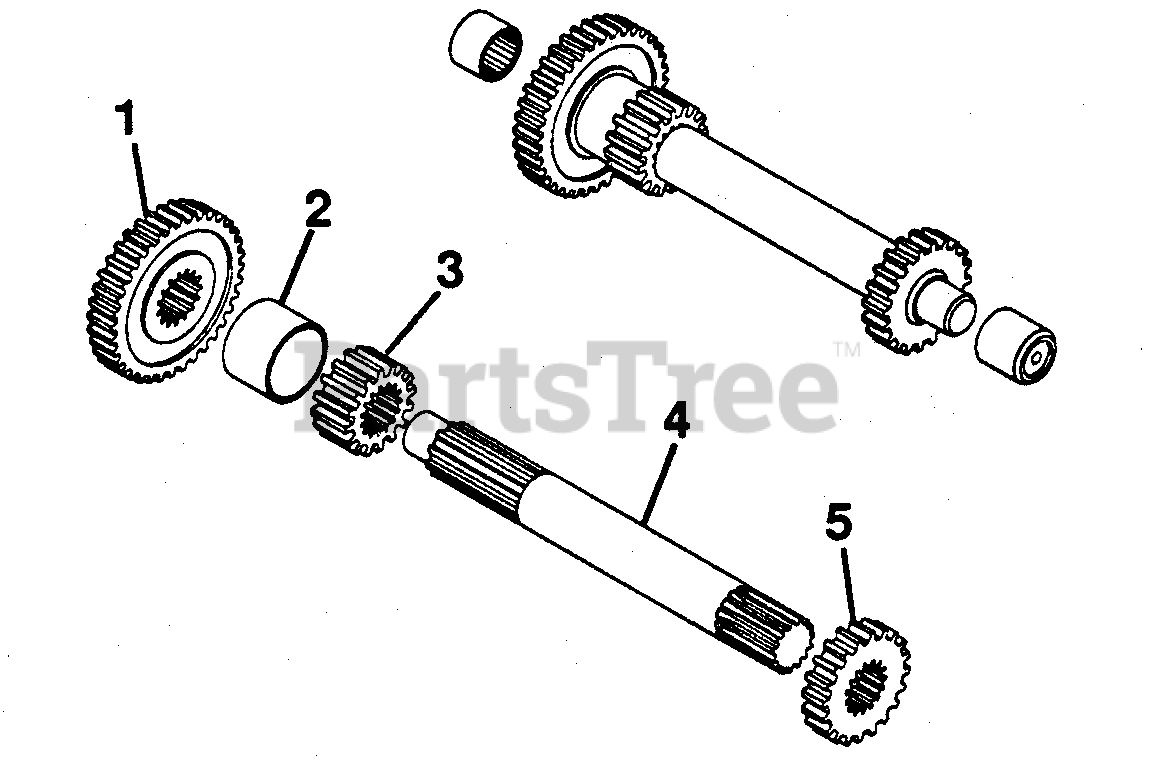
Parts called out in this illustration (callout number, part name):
1	Gear, 10 DP 30 Teeth x .500
2	Spacer, 1.027 x 1.125 x .550
3	Gear, 10 DP 16 Teeth x .750
4	Shaft, Splined
5	Gear, 10 DP 20 Teeth x .600
